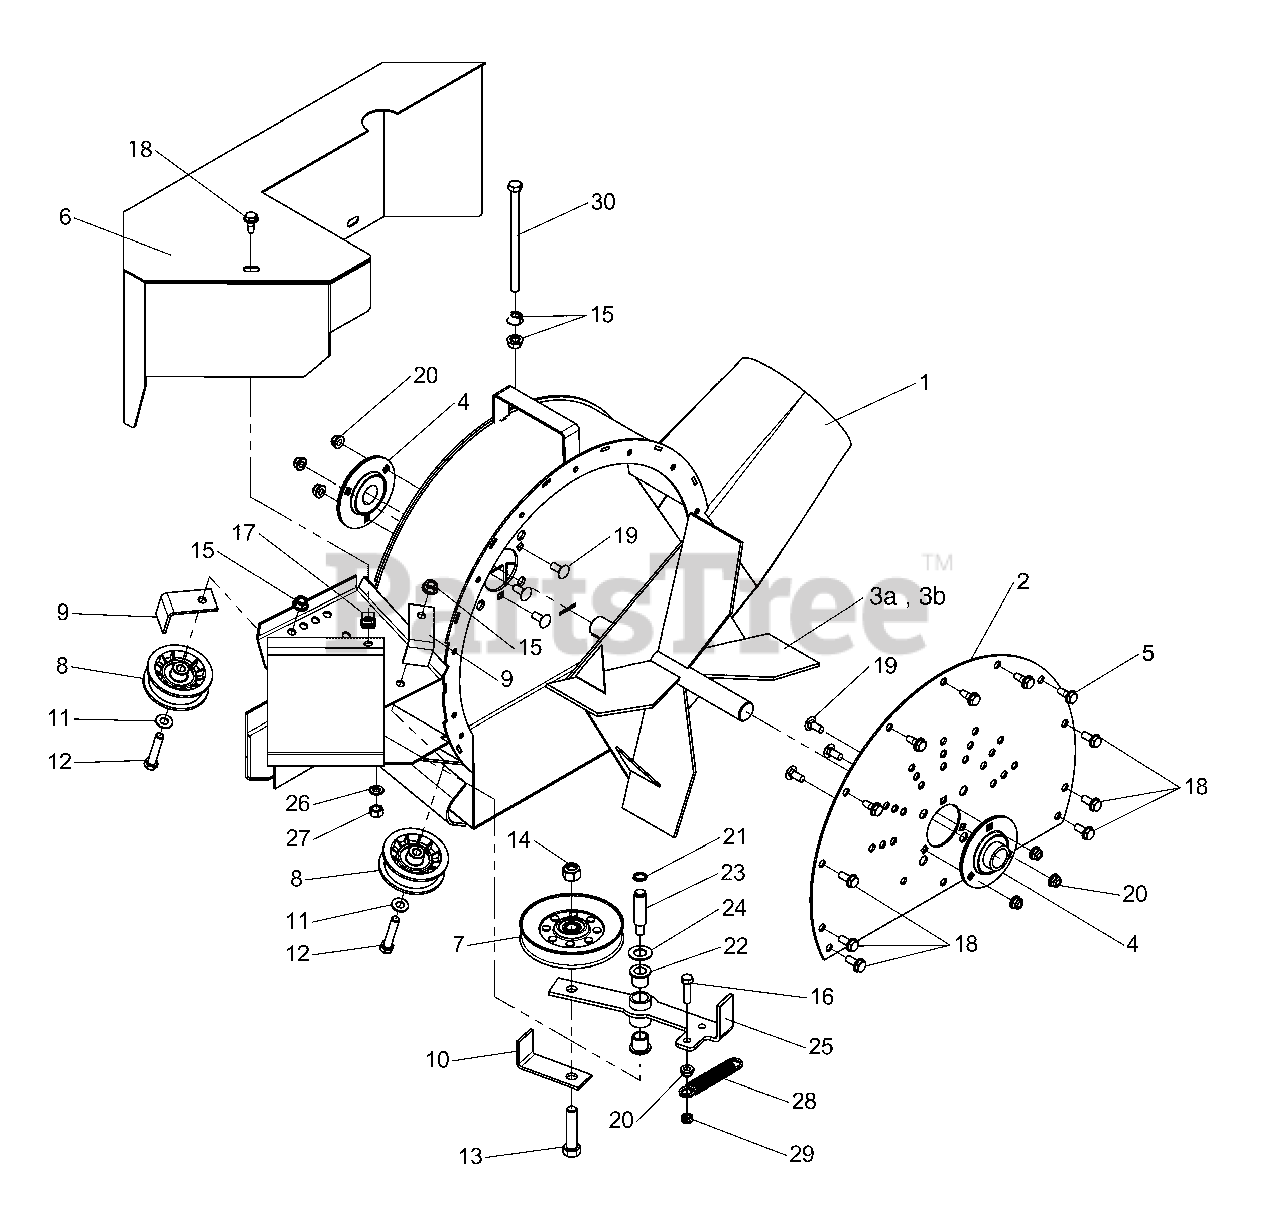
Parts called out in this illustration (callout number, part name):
1	BLOWER HOUSING
2	BACK PLATE
4	BEARING, FLANGE, 1" Bore
5	BOLT, 5/16-18 X 3/4" Self Tap
6	BELT GUARD
7	PULLEY, IDLER V-NOTCH, 5"
8	PULLEY, IDLER, 2.75 DIA X .376 ID
9	BELT KEEPER
10	KEEPER, BELT TENSIONER
11	WASHER, 3/8 SAE
12	BOLT, 3/8-16 X 2, GD5, CZ
13	BOLT, 1/2-13 X 2-1/4" GD5 CZ
14	NUT, 1/2-13 Hex Nylon Lock
15	NUT, 3/8-16 Hex Serrated Flange
16	BOLT, 5/16-18 X 1-1/4
17	U-CLIP, 5/16-18
18	BOLT, 5/16-18 X 5/8" Self Lock
19	CARRIAGE BOLT, 5/16-18 X 3/4
20	NUT, 5/16-18 Hex Nylock Flange
21	RETAINING RING, 1/2"
22	FLANGE BEARING, 9/16"
23	IDLER STUD
24	FLAT WASHER, 9/16" Narrow
25	WELD, IDLERARM, FAST-VAC - BLK
26	WASHER, 3/8 Lock
27	NUT, 3/8-24 Hex
28	SPRING, Extension
29	NUT, 5/16-18 Hex Center Lock
30	BOLT, 3/8-16 X 6" GD5 CZ
